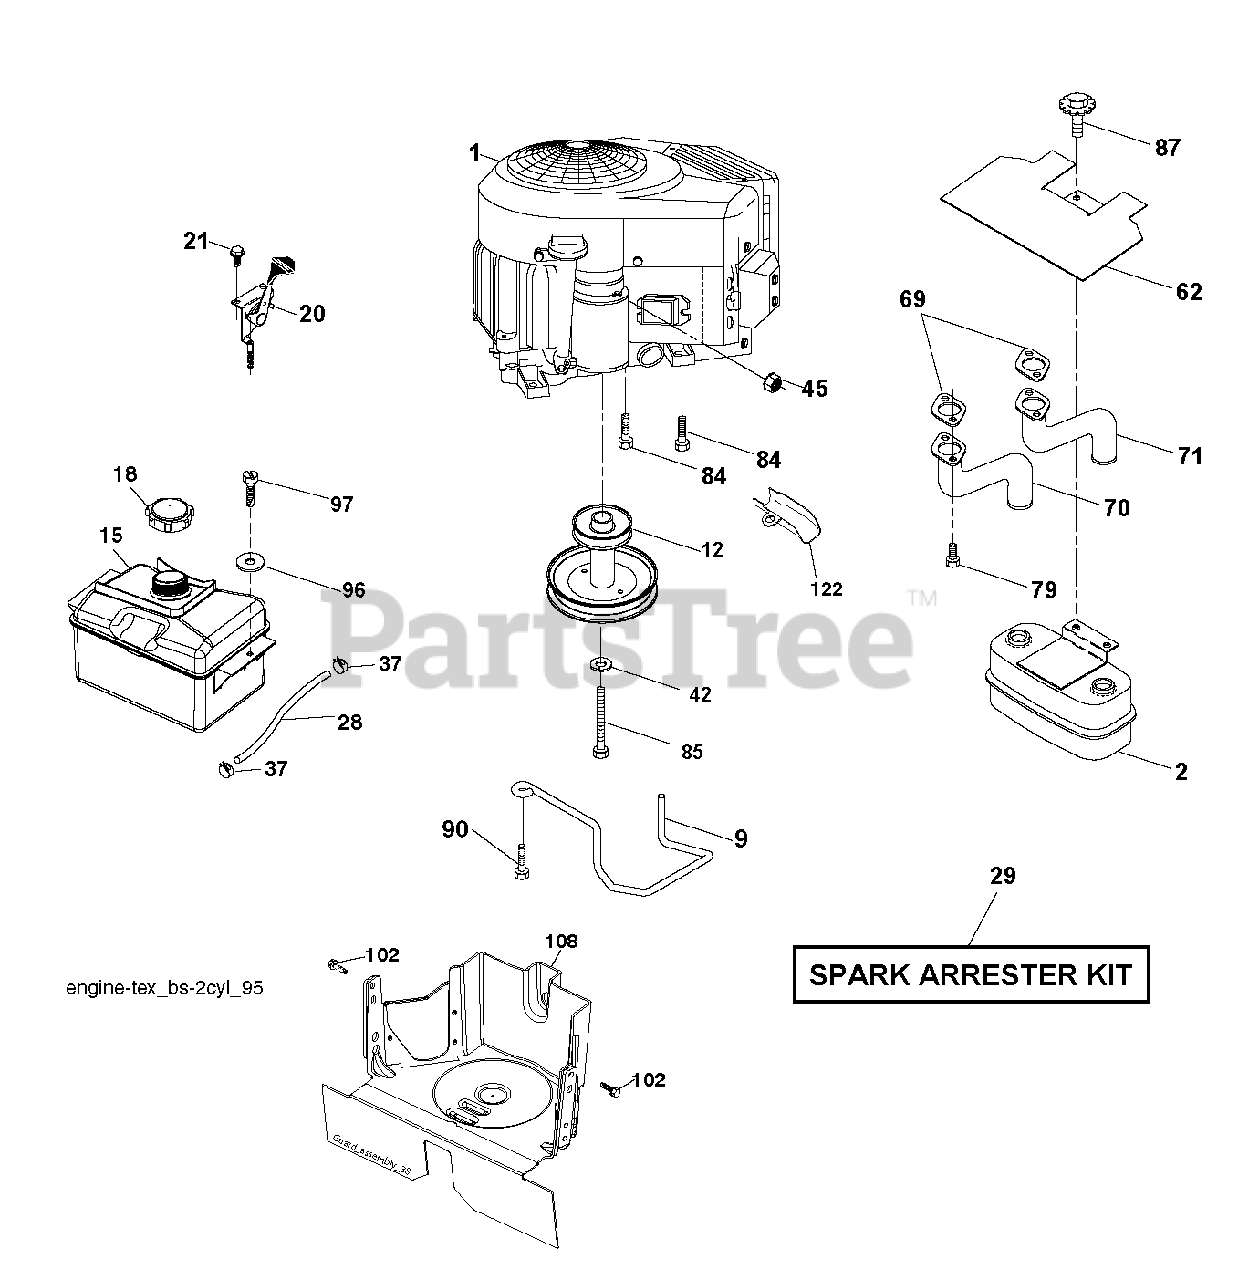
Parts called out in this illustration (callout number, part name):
2	MUFFLER.TWIN.CYL.LOW.TONE
9	Belt Keeper, 4 25"2 Blt 431
12	PULLY ENGINE
18	CAP ASM.FUEL.2.25"FR.
20	THROTTLE CABLE
21	SCREW.#10 X 0.750.BOS THREAD
28	LINE.FUEL.20
29	ARRESTER SPARK (OPTIONAL)
37	HOSE CLAMP
42	LOCKWASHER
45	NUT
62	SHIELD.HEAT.MUFFLER
69	REPL BY 532 27 22-93
70	TUBE MANIFOLD LH
71	EXHAUST TUBE RH
79	SCREW.SOCKET.HEAD.5/16-18
84	SCREW.3/8-16
85	BOLT HEX 7/16-20X4-1/4"
87	BOLT, 5/16-18 X 1 3/4
90	SCREW 3/8-16X1
97	SCREW HEXWSHR 1/4-20X3/4
102	SCREW 5/16-18X1
122	EXTENSION DRAIN OIL
